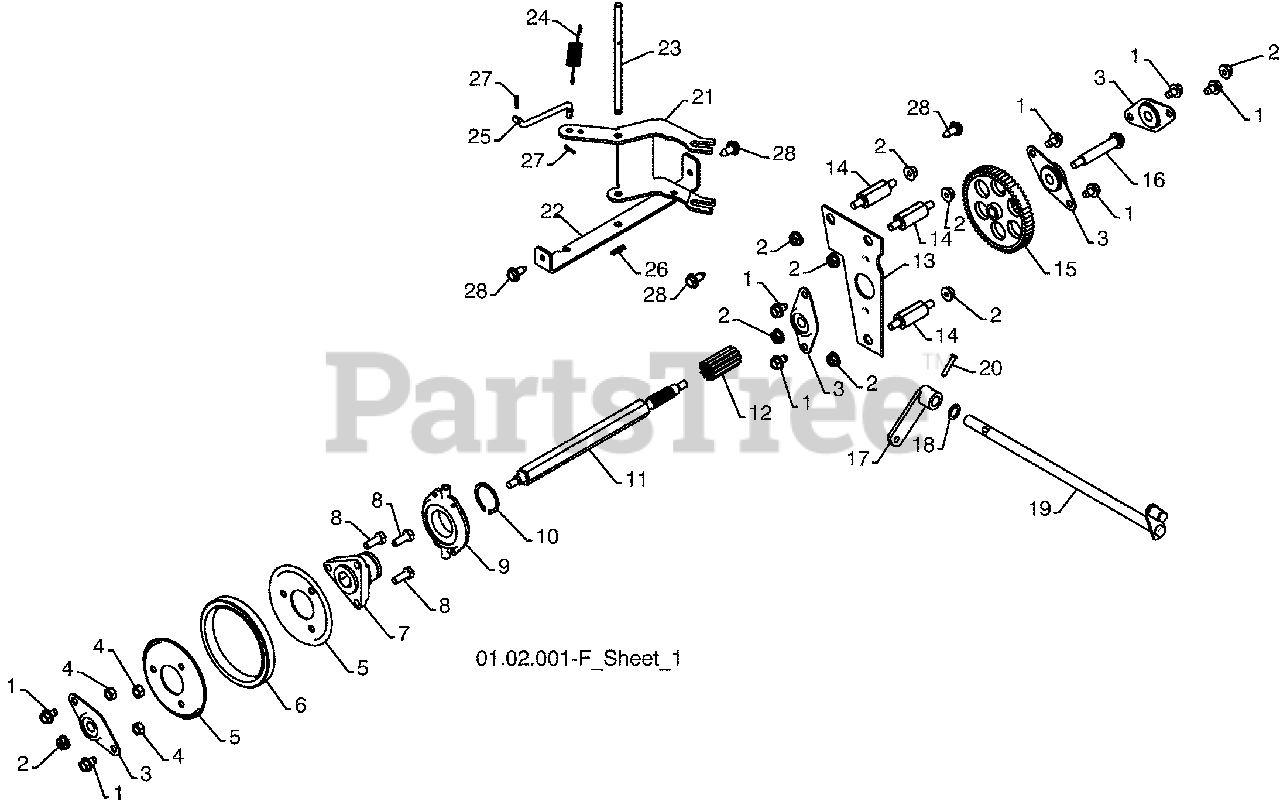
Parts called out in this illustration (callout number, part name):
1	SPEED SELECTOR HEAD ASSEMBLY
2	SCREW 10-24 X .625
3	DRIVE PLATE WELDMENT
5	TRUNNION BEARING ASSEMBLY
6	RETAINER
7	CARRIAGE BOLT 5/16-18 X .625
8	FLANGE BEARING
10	LEVER SHIFTER PLATE
11	SHIFTER SUPPORT BRACKET
14	SCREW 1/4-20 X .500
15	BOLT 5/16-18 X .500
16	DRIVE MOUNT PLATE
17	NUT 5/16-18
18	TRACTION PULLEY
20	LOCKWASHER 5/16
21	SCREW 5/16-18 X .750
22	IDLER BRAKE ARM
23	IDLER PULLEY
24	IDLER PIVOT BRACKET
26	SCREW 5/16-18 X 1.50
27	NUT 5/16-18
28	TRACTION SPRING
29	IDLER TRACTION ARM
30	IDLER PULLEY
31	SCREW 5/16-18 X 1.25
33	NUT 5/16-18
34	SCREW 3/8-24 X 1.38
35	LOCKWASHER 3/8
37	ENGINE TRACTION PULLEY
39	RETURN SPRING
40	BELT GUIDE
41	SCREW 5/16-18 X 1.00
42	BUSHING
43	LOCKWASHER 5/16
44	BRAKE SPRING
45	BOLT HEX HD WASHER 5/16
